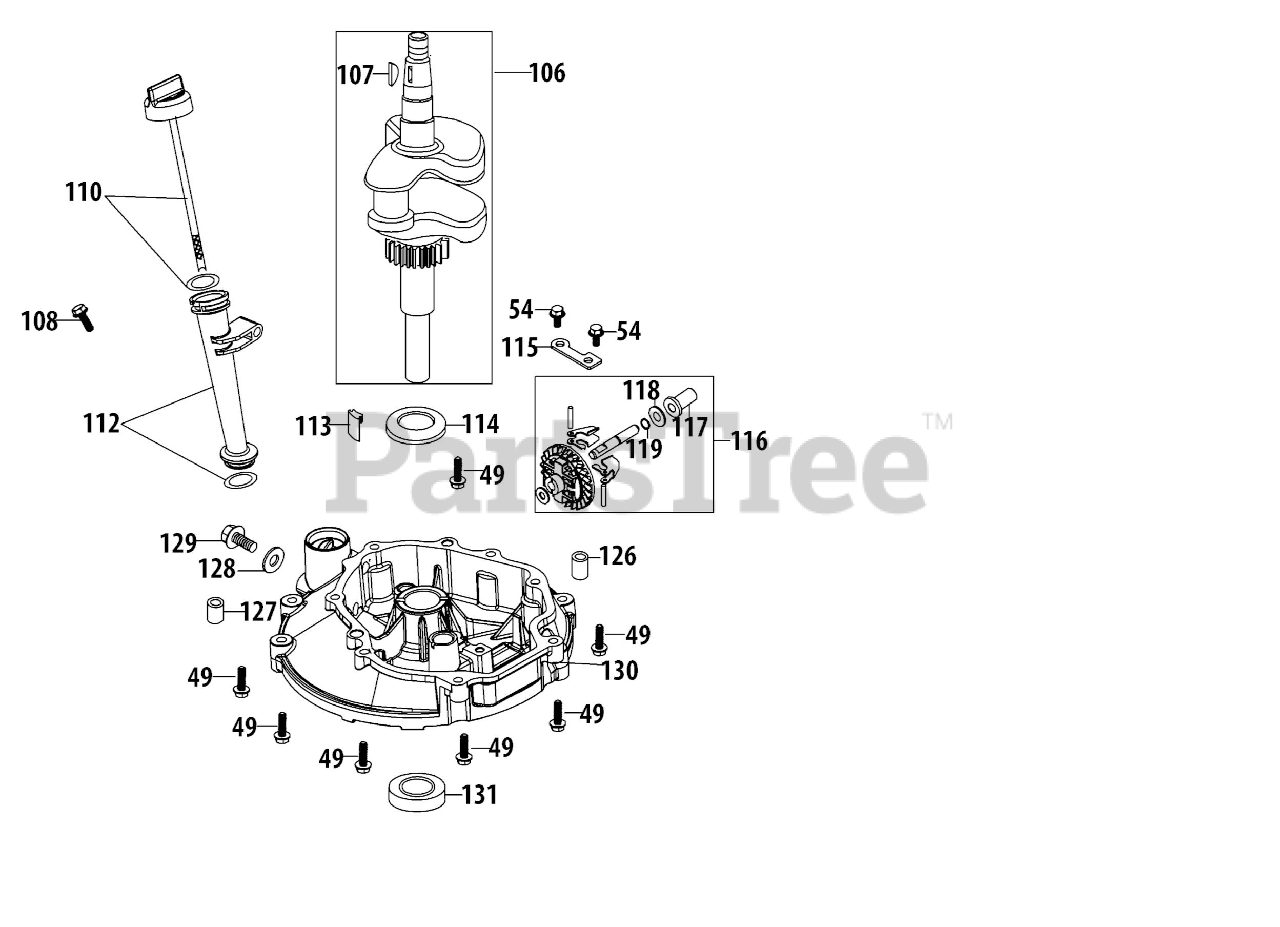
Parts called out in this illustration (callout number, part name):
49	Bolt M6X28 T/X/P Crankcase/Dp Stick
54	Bolt M6X14 Multi-Purpose
106	Crankshaft Assembly
107	Flywheel Key
108	Bolt M6X35 Af Base/Brake/Dipstick
110	Dipstick
112	Oil Fill Tube
113	Oil Return Seal
114	Crankshaft Thrust Washer
115	Governor Gear Mounting Plate
116	Governor Gear/Shaft Assembly
117	Governor Slide Cap
118	Governor Slide Cap Washer
119	Governor Shaft Stop Ring
126	Crankcase Cover Dowel Pin ?7?14
127	Crankcase Cover Dowel Pin ?9?14
128	Oil Drain Plug Washer
129	Oil Drain Plug
130	Crankcase Cover
131	Lower Crankshaft Seal
